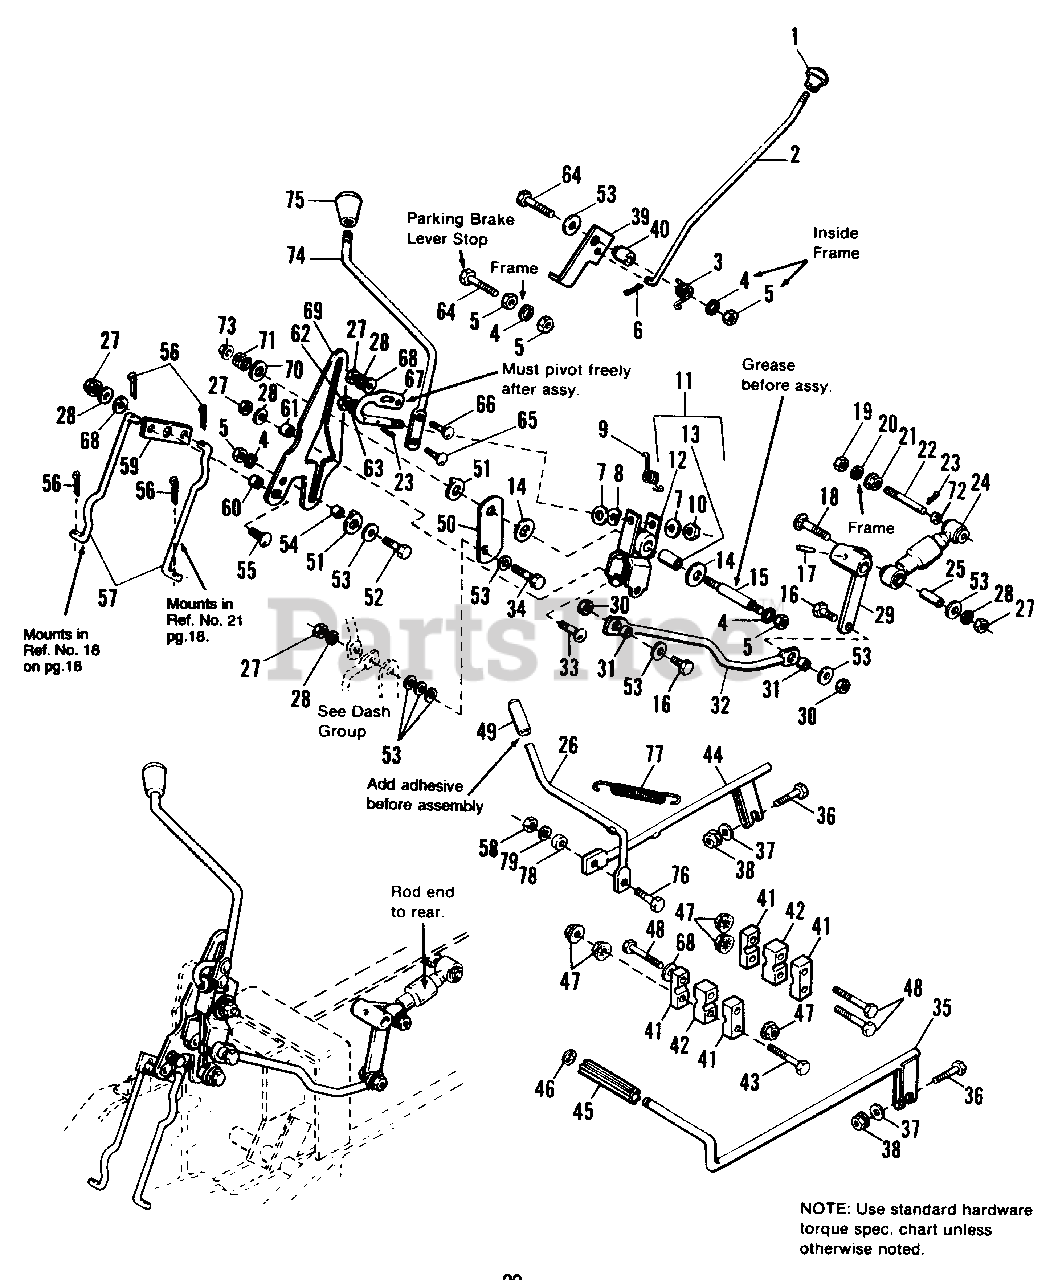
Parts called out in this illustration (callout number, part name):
1	KNOB, Parking Brake
2	ROD, Parking Brake
3	SPRING, Torsion
4	LOCKWASHER, 3/8
5	NUT, Hex, 3/8-16
6	PIN, Cotter, 1/16 x 3/4
7	WASHER, Plain, 1/2 x 1-1/4 x 5/64
8	WASHER, Curved, 1/2 x 1 x 1/64
9	SPRING, Torsion
10	NUT, Hex, Centerlock, Jam, 112-13
11	LEVER ASSY., Hyd. Control (Incl. Ref. Nos. 12 & 13)
12	LEVER ASSY., Hyd. Control
13	BEARING SLEEVE
14	DISC., Friction
15	SHAFT, Pivot
16	CAPSCREW, Hex Hd., 3/8-16 x 7/8
17	PIN, Spring, 1/4 x 1-1/4
18	BOLT, Carriage, 5/16-18 x 1-3/4
19	NUT, Hex, 7/16-14
20	LOCKWASHER, 7/16
21	NUT, Hex, Flange, Whizlock, 7/16-14
23	PIN, Cotter, 1/8 x 3/4
24	SHOCK ABSORBER
25	SPACER, 5/16
26	ROD, High-Low Control, Upper
27	NUT, Hex, 5/16
28	LOCKWASHER, 5/16
29	LEVER ASSY, Control
30	NUT, Hex, Centerlock, 3/8-16
31	SPACER, Ratchet Cage
32	ROD, Hydro Control
33	BOLT, Carriage, 5/16"-18 x 1-1/4
34	CAPSCREW, Hex Hd., 5/16-18 x 1-3/4
35	ROD & BRACKET ASSY., Diff. Lock
36	CAPSCREW, Hex Hd., 1/4-20 x 1-1/2
37	WASHER, Plain, 17/64 x 5/8 x 3/4
38	LOCKNUT, Hex, Flange, 1/4-20
39	LEVER, Parking Brake
40	SPACER, Parking Brake
41	BEARING HALF, Outer
42	BEARING Half, Center
43	CAPSCREW, Hex Hd., 5/16-18 x 2-3/4
44	ROD ASSY., Hi-Lo Control, Lower
45	PAD, Foot, Differential Lock
46	RING, Retaining "E"
47	LOCKNUT, Hex, Flange, 5/16-18
48	CAPSCREW, Hex Hd., 5/16-18 x 2-1/4
49	GRIP, Handle, Hi-Lo Control
50	BRACE, Hydro Control
51	WASHER, Lug
52	CAPSCREW, Hex Hd., 3/8-16 x 1-1/4
53	WASHER, Plain, 13/32 x 7/8 x 5/64
54	SPACER, 25/64 x 5/8 x 13/32
55	BOLT, Carriage, 5/16-18 x 7/8, Gr. 5
56	PIN, Cotter, 3/32 x 3/4
57	ROD, Ground Speed Brake
58	NUT, Hex Lock, 5/16-18
59	PLATE, Pivot
60	SPACER, 5/16 x 5/8 x 7/32
61	SPACER, 21/64 x 5/8 x 1/2
62	NUT, Hex, 1/4 x 20
63	LOCKWASHER, 1/4
64	CAPSCREW, Hex Hd., 3/8 16 x 1-3/4
65	BOLT, Carriage, 1/4-20 x 1-1/4
66	BOLT, Carriage, 5/16-18 x 1
67	ROD, Hydro Control
68	WASHER, Plain, 11/32 x 3/4 x 1/16
69	CAM PLATE, Hydro Lever
70	WASHER, Plain, 21/32
71	SPRING, Compression
73	LOCKNUT, Hex, Flange, 3/8-16
74	LEVER, Shift Control
75	KNOB, Speed Control
76	CAPSCREW, Hex Head, 5/16-18 x 1
77	SPRING
79	WASHER
